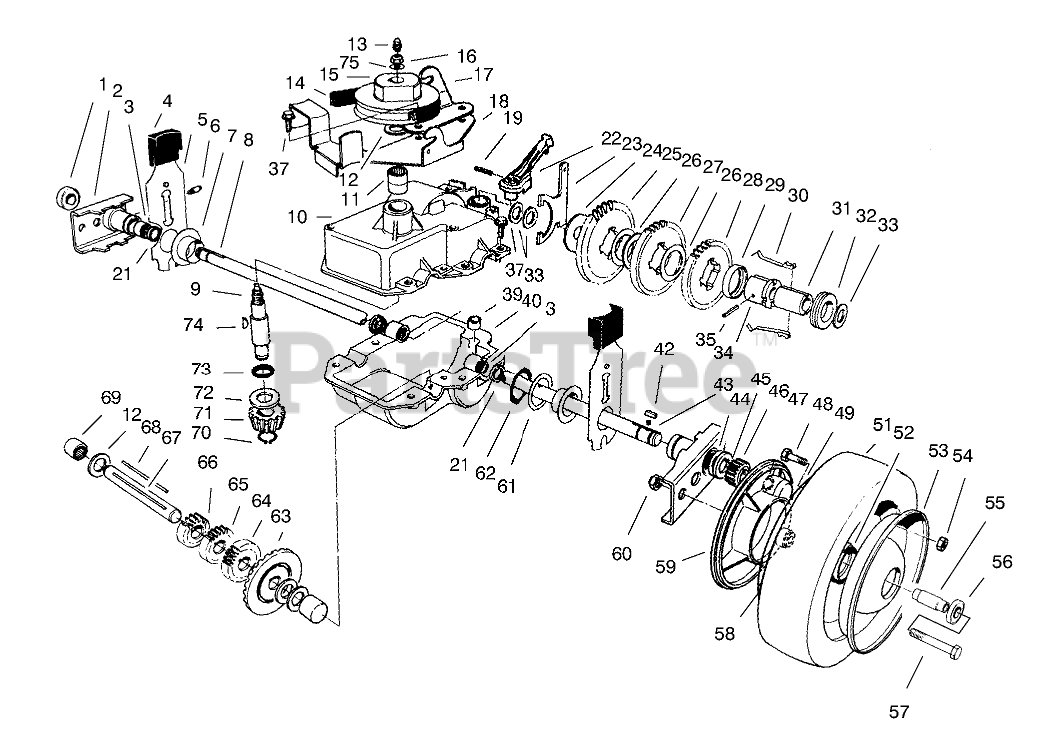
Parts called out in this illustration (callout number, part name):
1	BEARING-WHEEL
2	Pivot Arm Assembly (Incl. Ref. #1, 3, 6 & 21)
3	BEARING-ROLLER
4	KNOB-ARM
5	REAR SPRING ARM ASM
7	CAP-END
8	SHAFT-OUTPUT
9	Shaft-Input (Incl Ref. #13)
10	Upper Case Assembly (Incl. Ref. #11 & 73)
11	BEARING-NEEDLE
12	WASHER-THRUST
13	FITTING-GREASE, ZERK
14	V-BELT
15	PULLEY
16	NUT-HEX
17	Bracket-Traction Engage
18	Belt Guide Bracket
19	PIN-COIL
21	SEAL-OIL
22	LEVER-SHIFT
23	YOKE-SHIFT
24	WASHER
26	WASHER
27	GEAR-42T
28	GEAR-38T
29	RETAINER-KEY
30	KEY-SHIFT
31	SLEEVE
32	COLLAR-SHIFT
33	WASHER-PLAIN
34	SLEEVE-GEAR
35	PIN-GROOVE
37	SCREW-HWHTF
39	BUSHING-YOKE
40	CASE-GEAR, LOWER
43	SPRING-COMPRESSION
44	WASHER-THRUST, OUTER
45	WASHER-THRUST, OUTER
46	GEAR-PINION
47	RING-RETAINING
48	SCREW-HH
49	Wheel-Half
52	HUB-BEARING
53	Wheel-Half
54	NUT-LOCK, NI
55	SPACER-BEARING
56	BEARING-WHEEL
57	SCREW-HH
58	SPACER-COVER, WHEEL
59	COVER-WHEEL
60	NUT-LOCK, CONE
61	WASHER
62	RING-RETAINING
63	GEAR-BEVEL
64	GEAR-18T
65	GEAR-14T
66	GEAR-12T
67	SHAFT-INTERMEDIATE
69	BEARING-NEEDLE, CLOSED
70	RING-RETAINING
71	PINION-BEVEL
72	WASHER-THRUST
74	KEY-WOODRUFF
75	WASHER-FLAT
